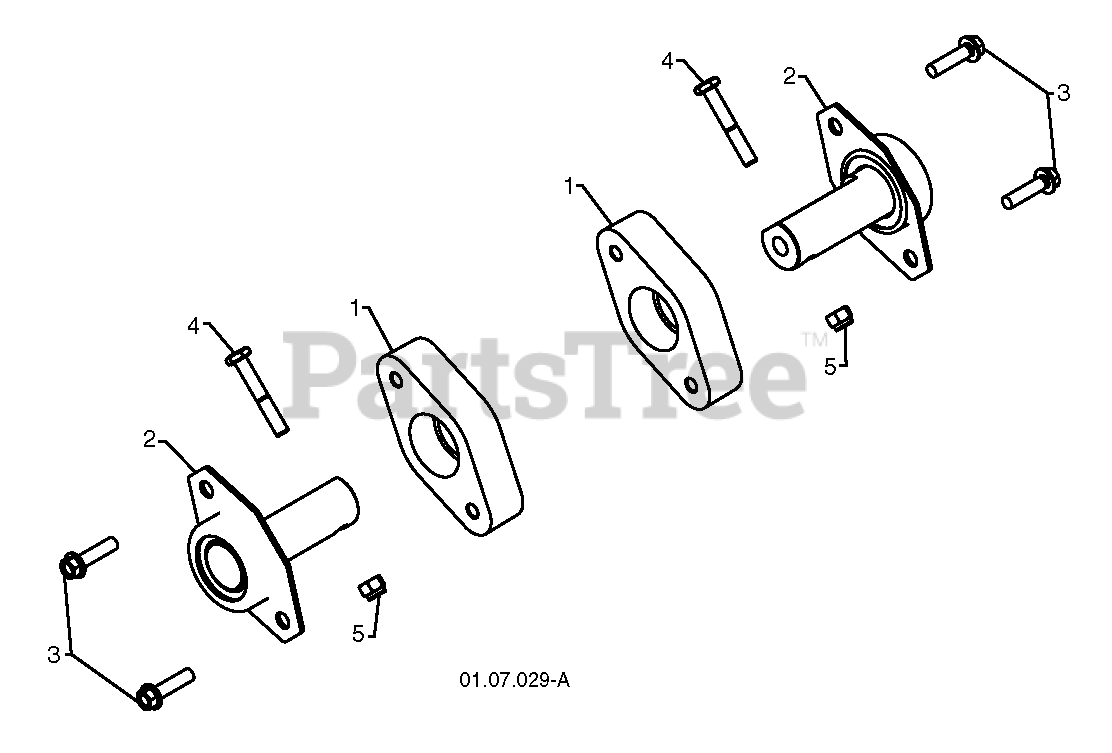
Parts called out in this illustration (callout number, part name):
1	RETAINER.PLASTIC
2	RP BEARING.BALL.AUGER.FLAT.
3	SCREW, HEX HD 5/16X1
4	SCREW.HEX.HD1/4-20X
5	LOCKNUT
